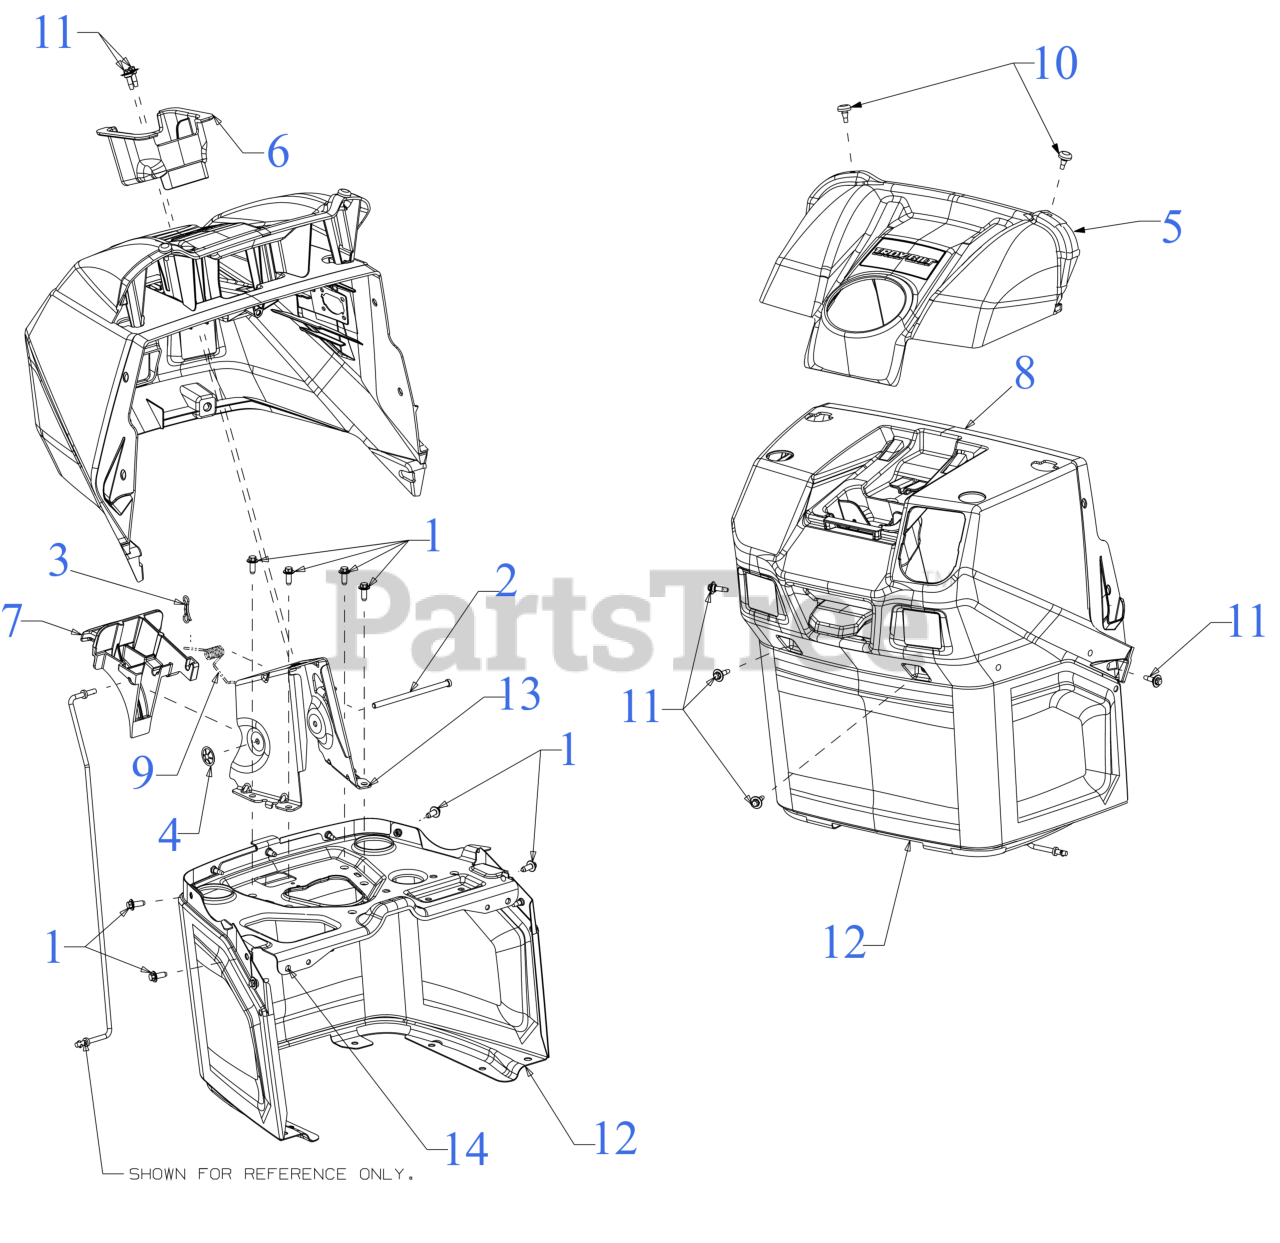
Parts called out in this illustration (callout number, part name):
1	SCREW M6-1 x .625
2	HINGE PIN .25 x 4.50
3	BOW TIE COTTER PIN 1/4-5/16
4	PUSH ON NUT
5	UPPER DASH CAP
6	STEERING SHAFT BEARING
7	BRAKE LEVER
8	DASHBOARD (UPPER) (NO USB)
9	TORSION SPRING .330 ID
10	RUBBER BUMPER
11	SHOULDER SCREW M6-1 .368 X.115
12	LOWER DASH
14	DASH/FUEL TANK PLATE
